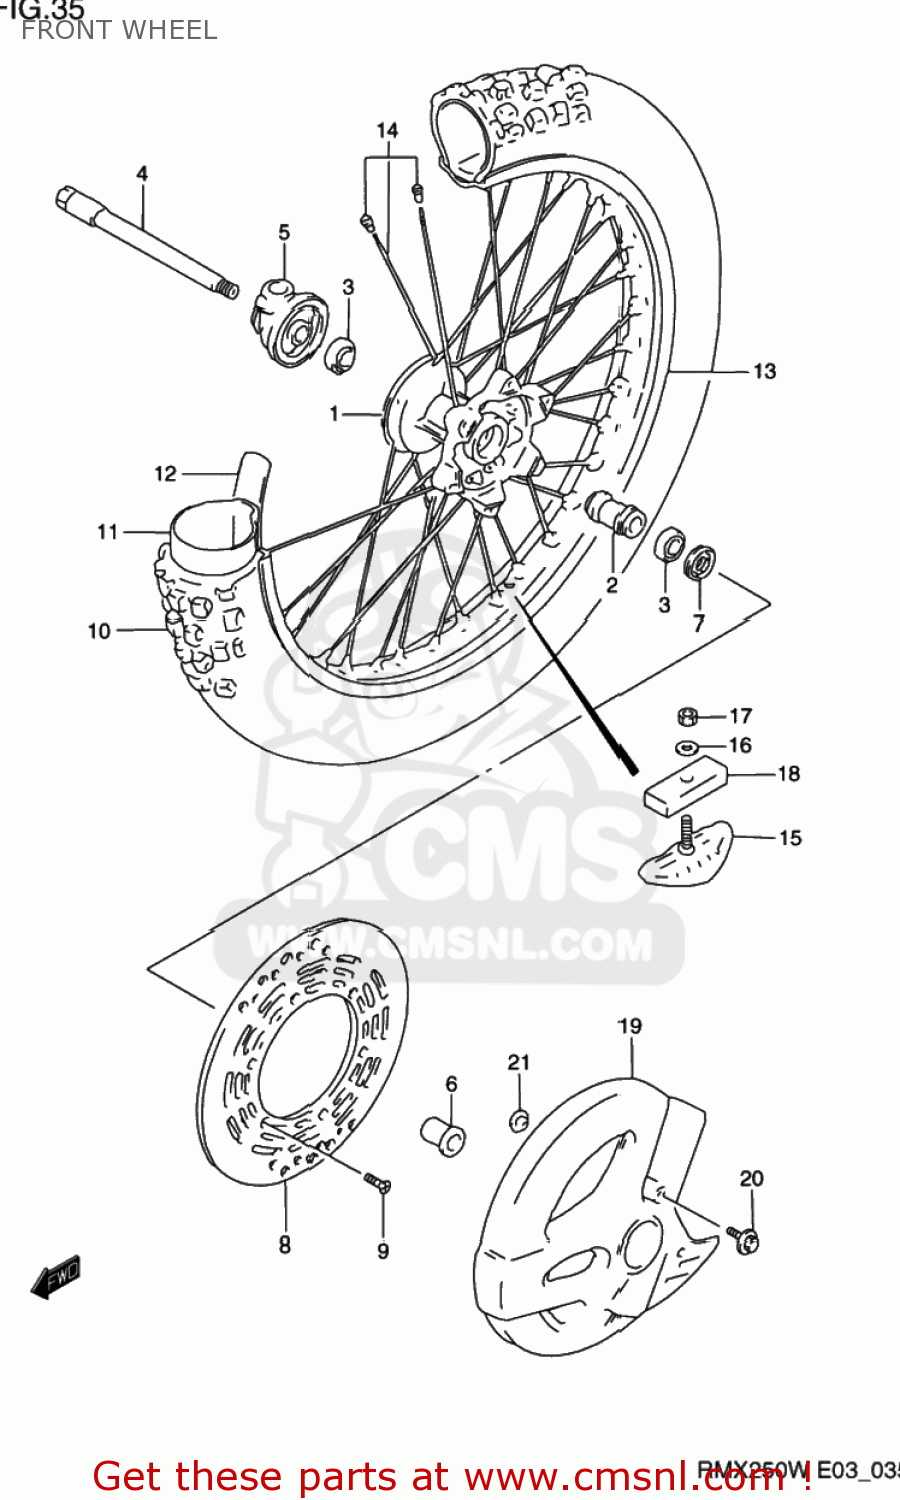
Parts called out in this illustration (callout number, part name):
1	HUB,FRONT WHEEL
2	SPACER,FR HUB BEARING
3	BEARING
4	AXLE,FR
5	BOX ASSY,SPEEDOMETER GEAR
6	SPACER,FR AXLE,L
7	SEAL,OIL(23X35X6)
8	DISC,FR BRAKE
9	SCREW
10	TIRE,FRONT 80/100-21
11	TUBE
12	PROTECTOR,WHEEL INNER
13	RIM,FRONT WHEEL (1.60X2
14	SPOKE SET,FR WHEEL
15	STOPPER,BEAD
16	WASHER
17	NUT
18	CUSHION,BEAD STOPPER
19	COVER,FRONT BRAKE DISC
20	BOLT(6X16)
21	WASHER
